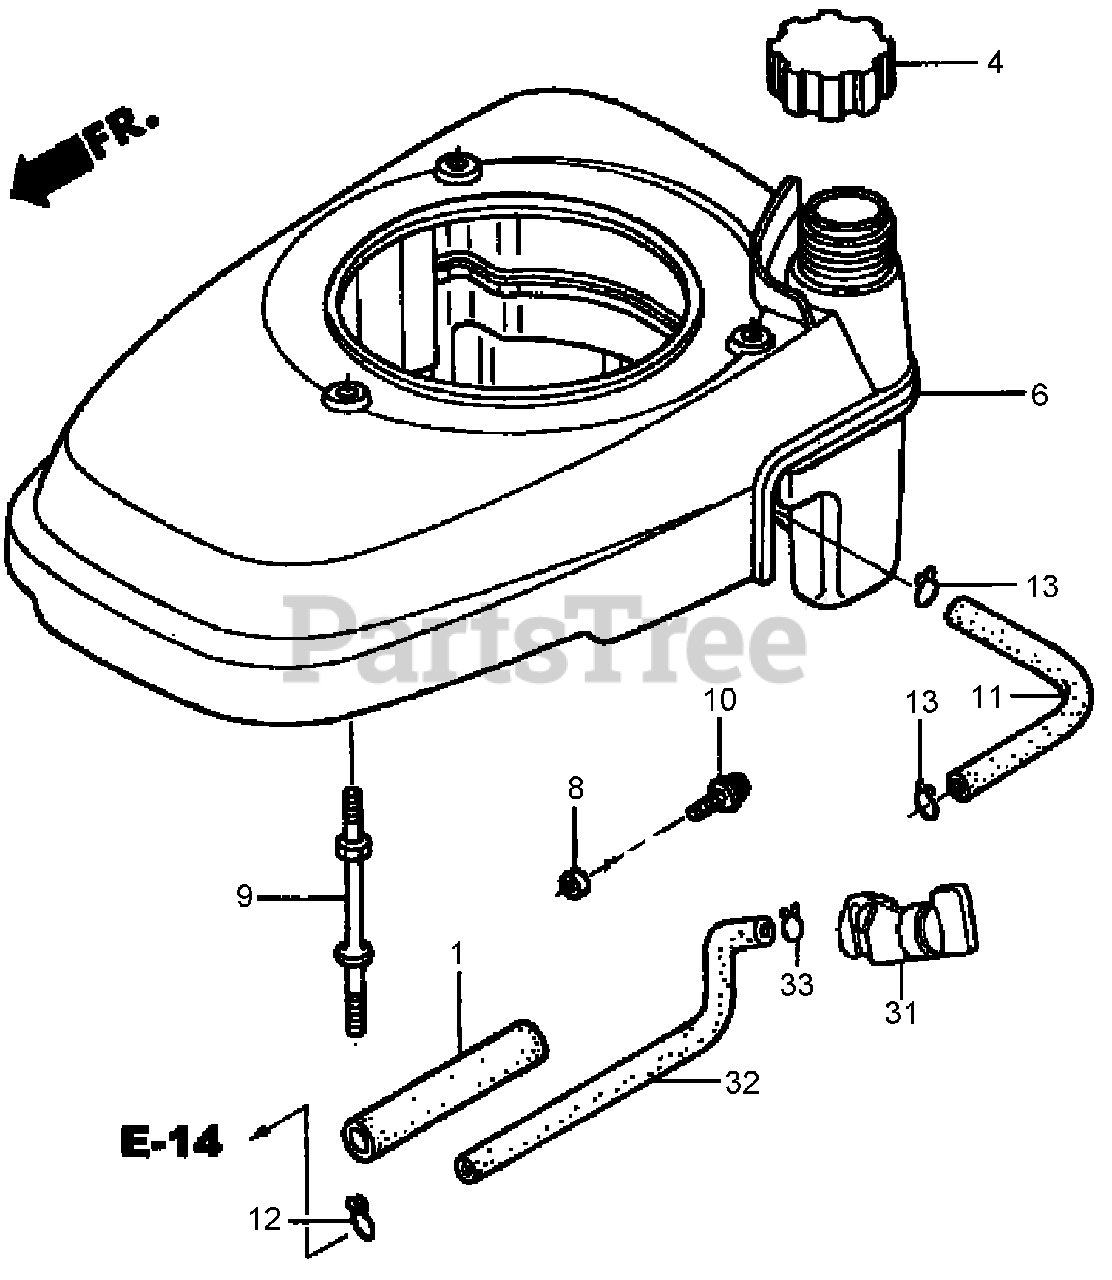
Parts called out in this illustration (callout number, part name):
1	SUPPORTER-RUBBER (107 mm)
4	FUEL TANK CAP ASM
6	COVER-FAN
8	COLLAR-PETCOCK, FUEL
9	BOLT-STUD (H T 42.5MM)
10	SCREW-WASHER (5X10)
11	FUEL-HOSE (5.5X8000) (5.5X100)
12	CLIP-TUBE (B8)
13	CLIP-TUBE (B10)
31	PETCOCK ASM
32	TUBE-FUEL
33	CLIP-TUBE (B8)
